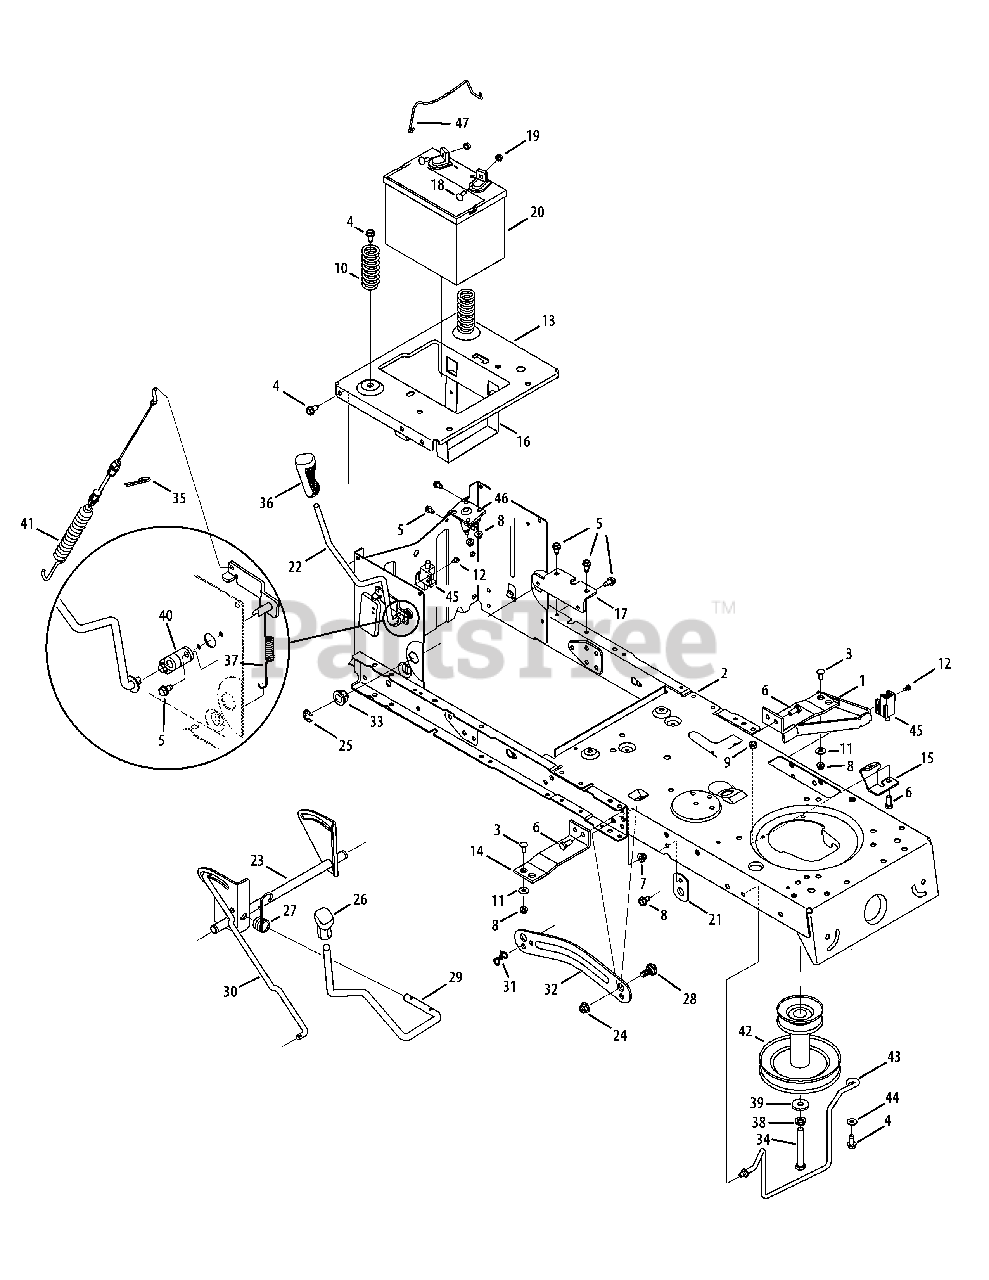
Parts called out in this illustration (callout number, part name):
1	Support Bracket
2	Frame Assembly - Black
2	Frame Assembly - Green
3	Screw Carriage, 1/4-20 x .62
4	Screw 5/16-18 x .750
5	Screw, 1/4-20 x .500
6	Hex Screw, 5/16-18 x .75
7	Flange Lock Nut, 5/16-18
8	Flange Lock Nut, 1/4-20
9	Hexlock Nut, 5/16-18
10	Compression Spacer, 1.28 x 3.125
11	Flat Washer, .28 x .74 x .063
12	Shoulder Spacer, 10-32 x .500
13	Seat Frame Bracket
14	Running Board Bracket
15	Support Frame Bracket
16	Battery Bracket
17	Brace Frame Bracket
18	Hex Head Flange, 1/4-20 x .75
19	Sems Nut, 1/4-20
20	230 CCA Battery
21	Support Bracket
22	PTO Handle Assembly
23	Lift Assembly
24	Flange Lock Nut, 3/8-16
25	E Ring
26	Handle Grip, 1/2
27	Torsion Spring
28	Shoulder Bolt, 3/8-16 x .625 x .175
29	Deck Lift Handle
30	Lift Rod
31	Bow-tie Cotter Pin
32	Lift Arm, RH
32	Lift Arm, LH
33	Hex Flange Bearing
34	Hex Screw, 7/16-20 x 3.25
35	Click Pin, .092 x 1.64
36	Handle Grip, 3/8
37	PTO Spring Extension
38	Regular Duty Washer Lock, 7/16
39	Flat Washer, .450 x 1.250 x .164
40	PTO Bearing
41	Deck Engage Cable
42	Engine Pulley, 3.39 x 6.12, 38/42"
43	Belt Keeper
44	Flat Washer, .406 x .875 x .059
45	Switch Interlock
46	12V Solenoid
47	Rod Asm, Batt
